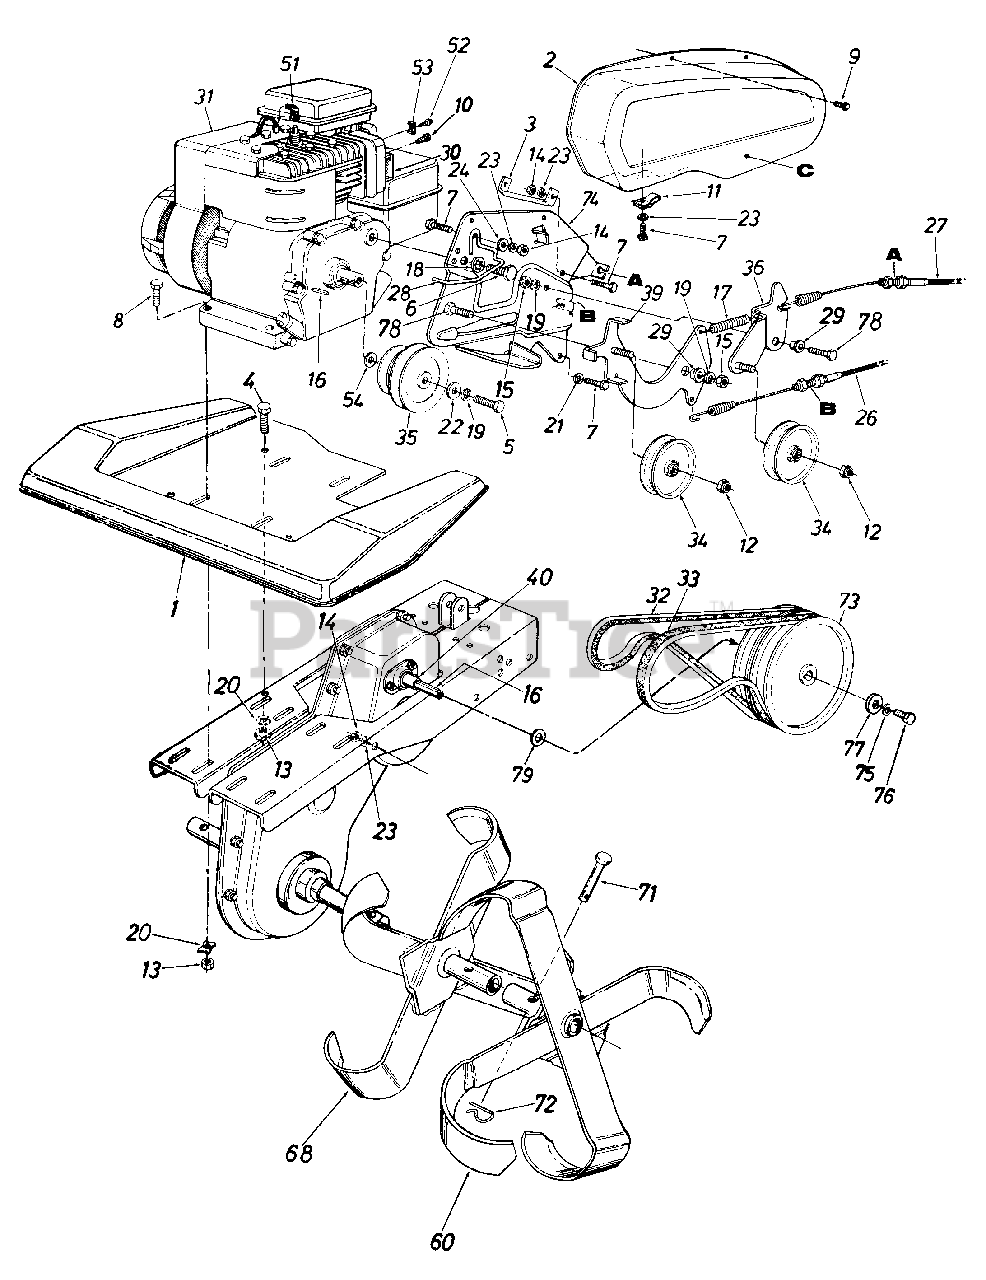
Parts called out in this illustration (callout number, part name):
4	Hex Bolt 5/16-18 x .75" Lg.
5	Hex Bolt 3/8-24 x 1.25n Lg.
6	Hex Bolt 5/16-24 x .62" Lg.
7	Hex Bolt 1/4-20 x .85" Lg.
8	Hex Bolt 5/16-18 x 1.5" Lg.*
9	Hex Wash. Hd. Tap Scr. 1/4-20 x .5" Lg.
10	Hex Wash. Hd. Slotted Scr. #8-32 x .38"
11	Speed Nut 1/4-20 Thd.
12	Hex L-Nut 3/8-24 Thd.
13	Hex Nut 5/16-18 Thd.
14	Hex Nut 1/4-20 Thd.
15	Hex L-Nut 3/8-16 Thd.
16	Sq. Key 3/16 x 1.5" Lg.
17	Extension Spring 2.03 Lg.
18	L-Wash. 5/16" I.D.
19	L-Wash. 3/8" I.D.
20	Spec. L-Wash. 5/16" I.D.
21	Spr. Wash. .265" I.D. x .562" O.D.
22	Fl-Wash. 818" I.D. x 1" O.D. x 1.27n
23	L-Wash. 1/4" I.D.
24	Fl-Wash. .25 I.D. x .62 O.D.
26	Clutch Control Cable
27	Clutch Control Cable
28	Belt Guard Rod
29	Shld. Spacer .380 I.D.
30	Muffler Deflector
31	Engine
32	V-Belt
33	V-Belt
34	Fl-Idler w/Flanges 3.12 O.D. x .75
35	Engine Pulley
40	Spacer .635 I.D.
51	Spark Plug Boot
52	Hex Sems Scr. #10-32 x .62" Lg.
53	Casing Clamp
54	Fl-Wash. .75" I.D. x 1.5" O.D. x .12"
72	Intern. Cotter Pin
73	Transmission Pulley 6" Dia.
74	Clutch Mtg. Plate
75	L-Wash. 5/16" I.D.
76	Patch Bolt 5/16-18 x 1" Lg.
77	Fl-Wash. 5/16" I.D.
78	Hex Bolt 3/8-24 x 1.0" Lg. (Grade 5)
79	Fl-Wash. .635" I.D. x 1.25" O.D.
